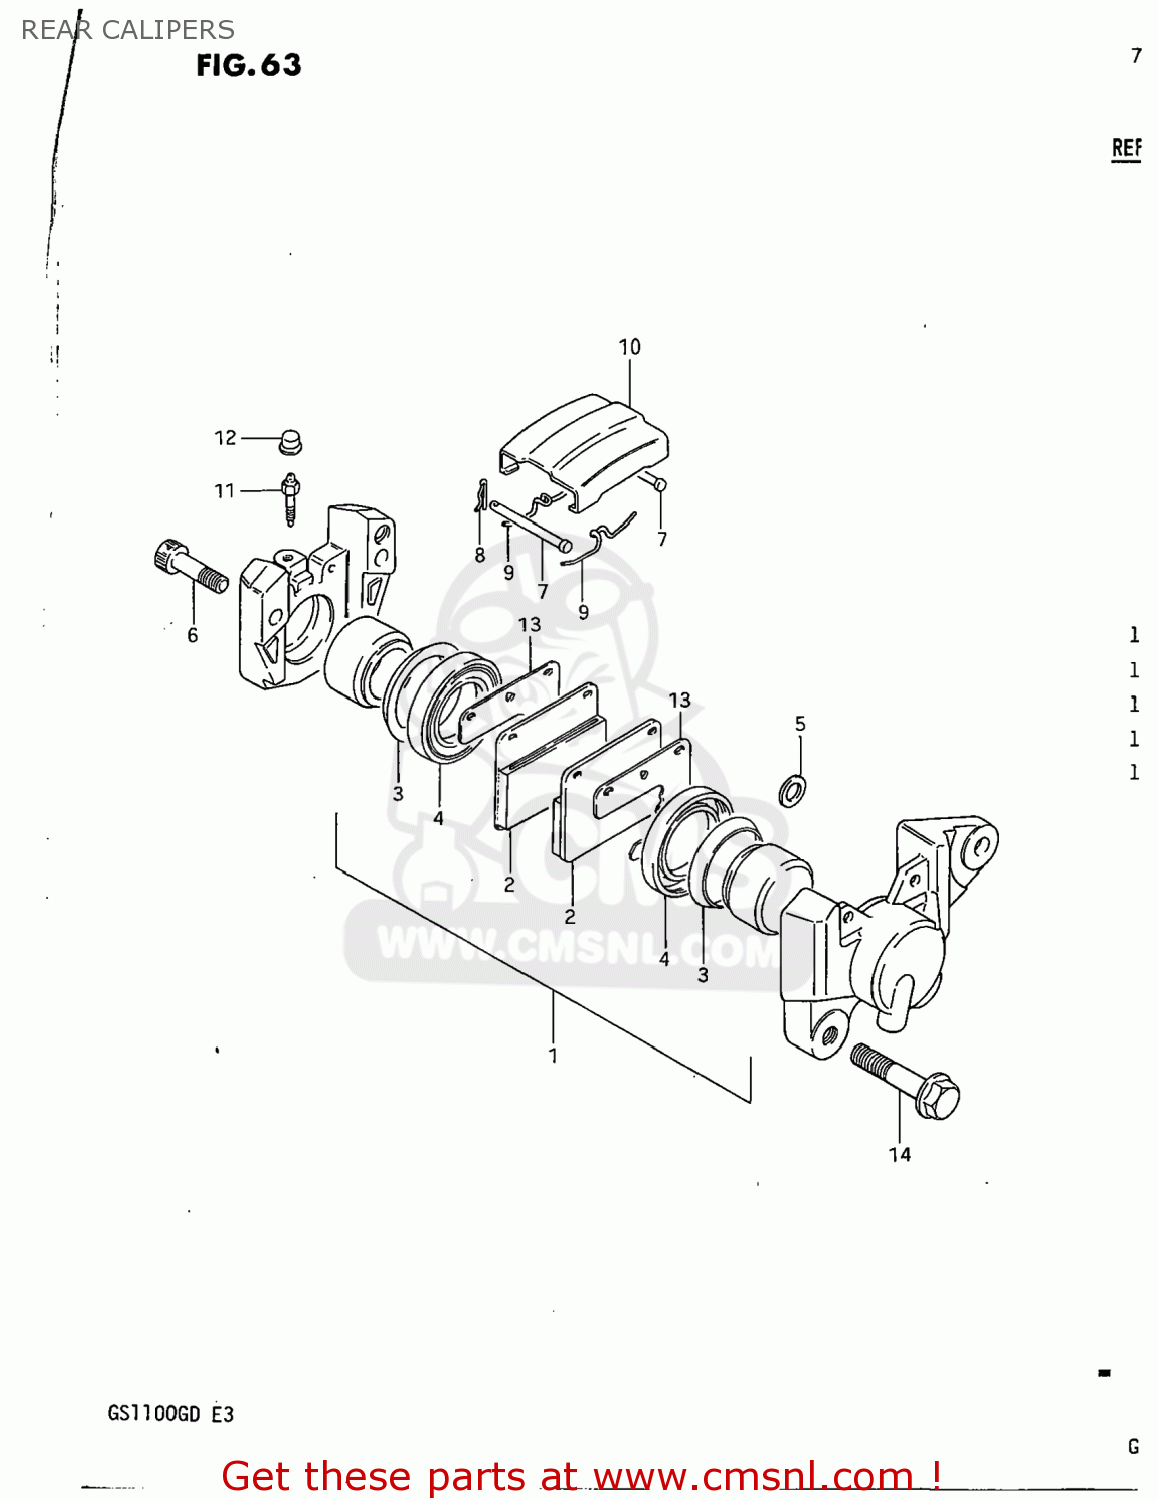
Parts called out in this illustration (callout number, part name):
1	PISTON SET
2	PAD,BRAKE
3	SEAL,PISTON
4	BOOT,PISTON
5	SEAL,JOINT
6	BOLT,CALIPER HOUSING
7	PIN,PAD
8	CLIP,PAD PIN
9	SPRING
10	COVER,DUST
11	BLEEDER
12	CAP,BREATHER
13	SHIM,RR CALIPER
14	BOLT
